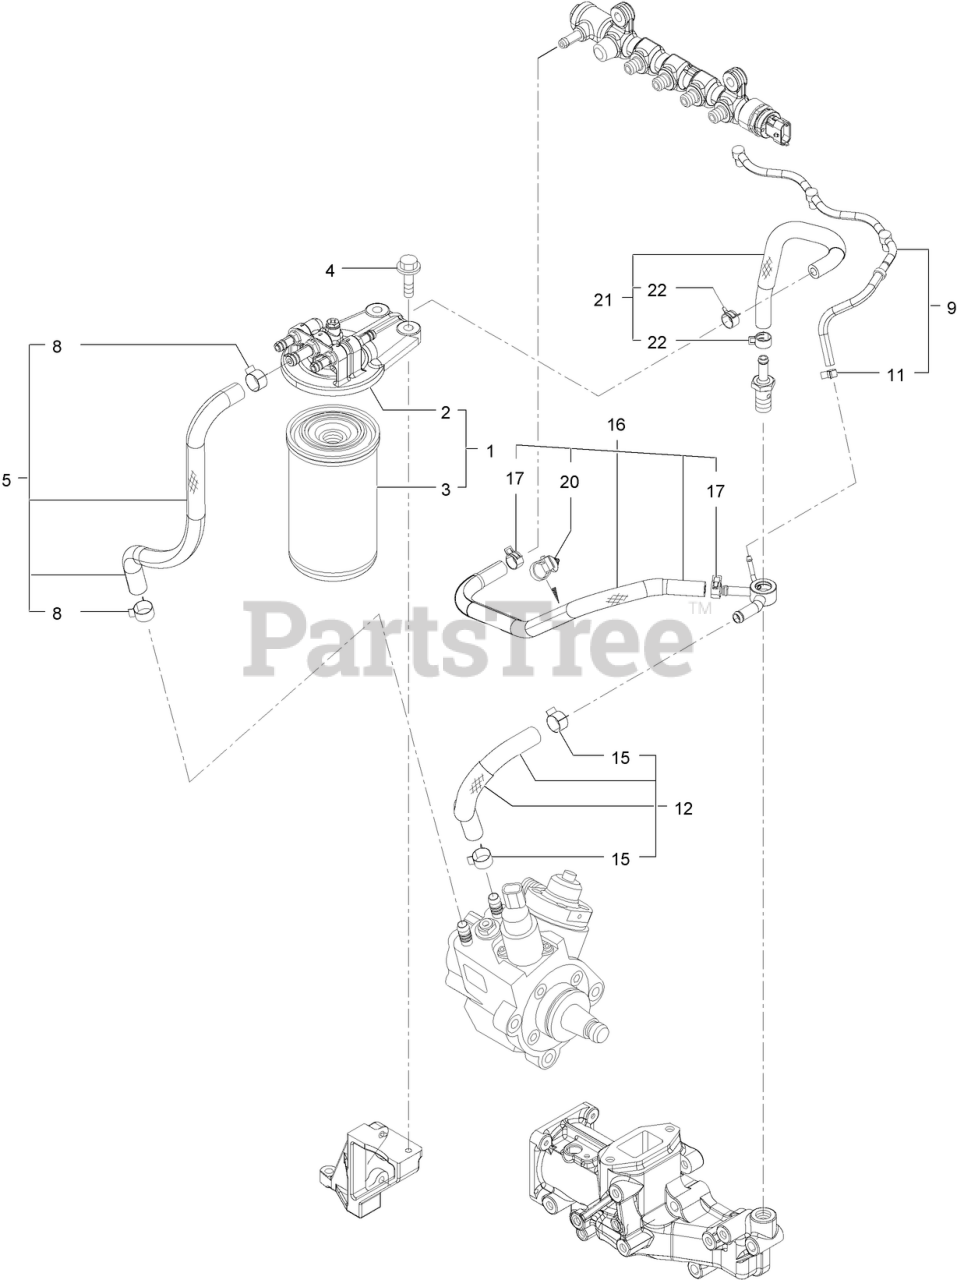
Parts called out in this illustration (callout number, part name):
1	FUEL/OIL FILTER ASM
2	FUEL/OIL FILTER BRACKET ASM
3	FILTER-FUEL
5	FUEL PIPE ASM
8	CLAMP-HOSE
9	PIPE ASM-FO RETURN
11	CLAMP-HOSE
12	FUEL PIPE ASM
15	CLAMP-HOSE
16	FUEL PIPE ASM
17	CLIP-HOSE
20	BAND-CLIP
21	FUEL PIPE ASM
22	CLIP-HOSE
